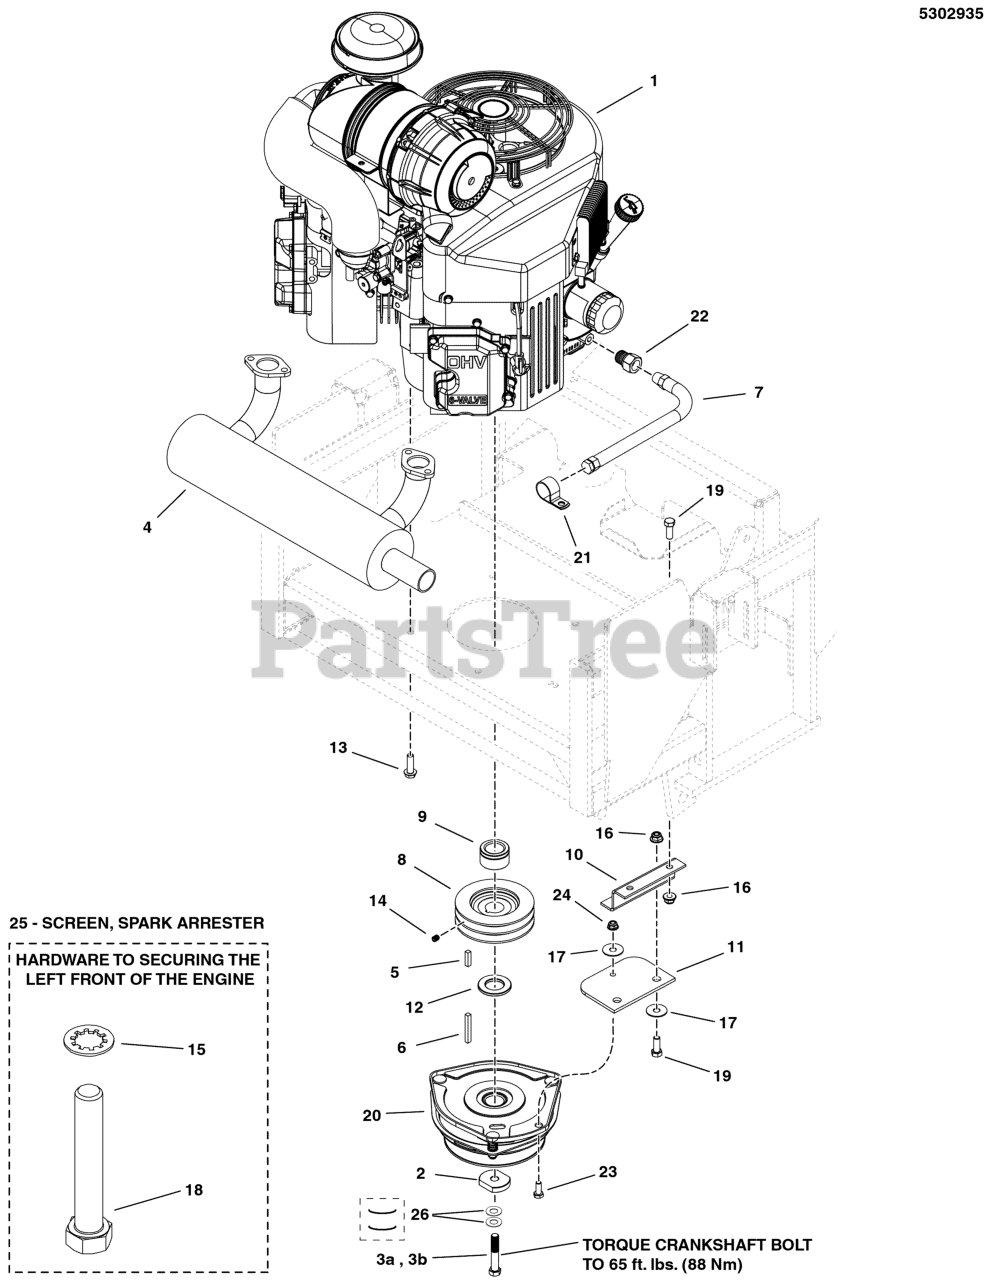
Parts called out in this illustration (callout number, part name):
1	ENGINE, KAWA, DFI
2	SPACER, .45 X 1.88 X .38
4	MUFFLER 37 HP KAWASAKI
5	KEY, 1/4 SQ X 1
6	KEY, 1/4 SQ X 2
7	HOSE, OIL DRAIN
8	PULLEY, CRANKSHAFT, 1.126 ID X 4.75 OD
9	SPACER, 1.13 X 1.75 X 1.03, CZ
10	ANCHOR, CLUTCH - BLK
11	CLUTCH ANCHOR PAD
12	SPACER, 1.13 x 2.00 x .19
13	BOLT, HEX FLG, SER, GD5 3/8-16 X 1-1/4" PACH CZ
14	SET SCREW, 5/16-18 X 3/8, KNURL, W/PATCH
15	WASHER, 3/8" ID, INTERNAL TOOTH
16	NUT, 3/8 - 16 HEX NYLOCK FLANGE
17	WASHER, 3/8" Fender
18	BOLT, 3/8-16 X 2-1/4" GD5 TFL
19	BOLT, 3/8-16 X 1" GD5 CZ
20	CLUTCH, OGURA, 250 ft lbs - 1.13"
21	CLAMP, VINYL INSULATED, 1.00
22	ADAPTER, Oil Drain
23	BOLT, 5/16-18 X 1" GRD5 YZ
24	NUT, 5/16-18 HEX NYLOCK FLANGE NUT
25	SCREEN, SPARK ARRESTER (SV)
26	BELLEVILLE WASHER, 1.1875 X .442 X .098
